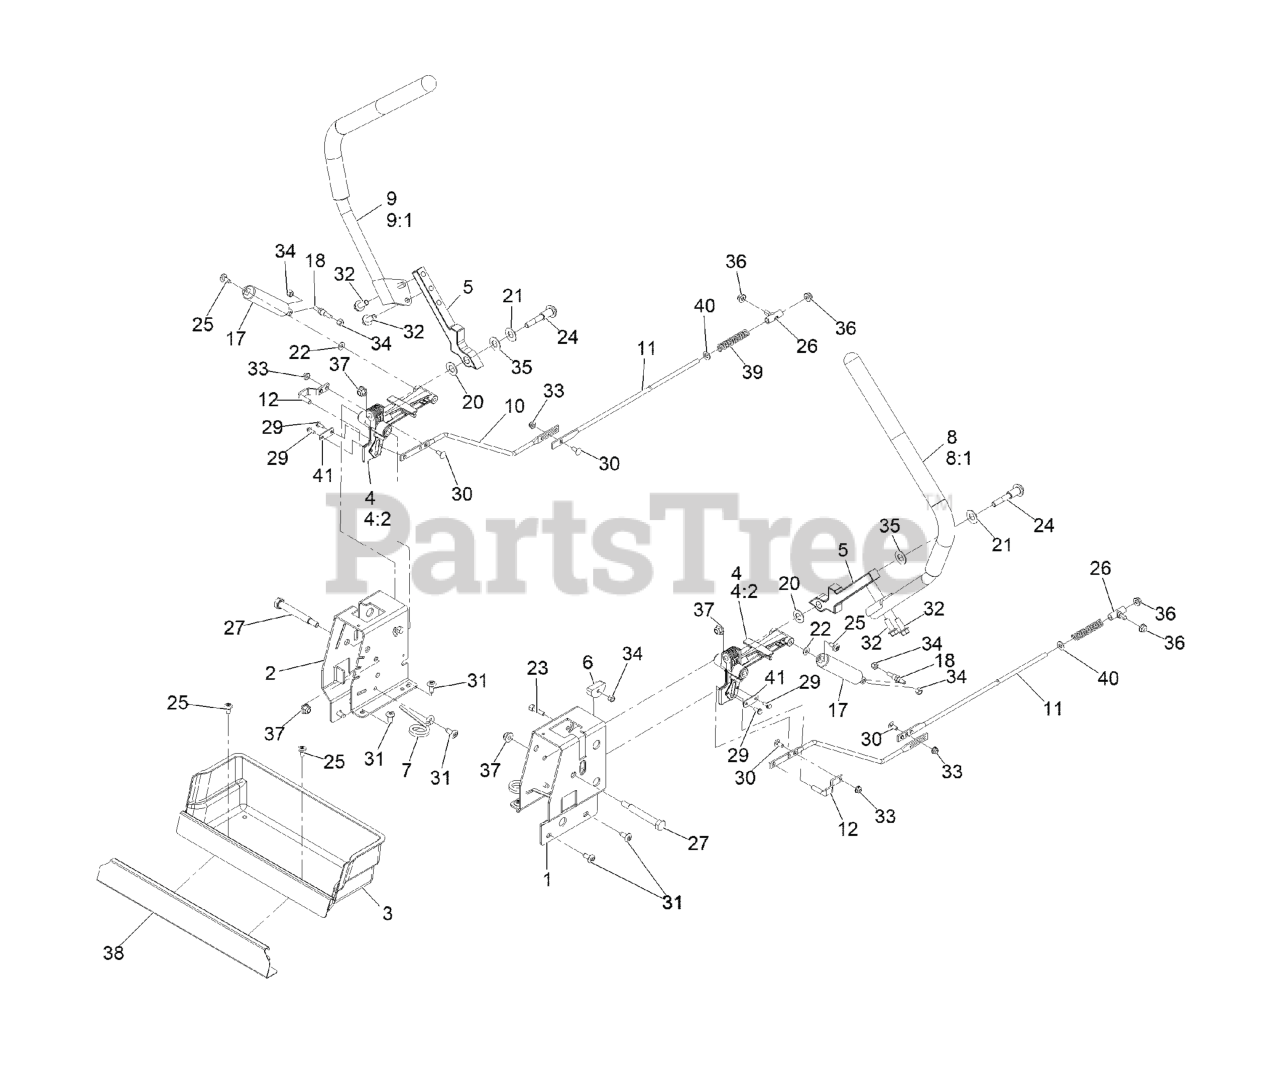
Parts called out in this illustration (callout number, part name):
1	PLATE-CONTROL BOX, LH
2	PLATE-CONTROL BOX, RH
3	BOX, STORAGE
4	ACTUATOR ARM ASM
4:2	BUSHING-FLANGE
5	ARM-CONTROL
6	ECCENTRIC
7	SPRING-TORSION
8	HANDLE-CONTROL, LH
9	HANDLE-CONTROL, RH
10	ROD-HYDRO, FRONT
11	ROD-HYDRO, REAR
12	PIN-ROD, HYDRO
17	DAMPER-NON CAVITATING
18	STUD-DAMPER
20	WASHER-NYLON
21	WASHER-BELLEVILLE
23	BOLT-PIVOT, ECCENTRIC
24	BOLT-PIVOT
25	SCREW-SHOULDER
26	Rod-Hydro
27	BOLT-PIVOT
29	SCREW-TAPTITE
30	SCREW-CARR
32	SCREW-HHF 3/8-16 X 1
34	NUT-LOCK, NI
37	NUT-HF, NI
38	PLATE-KICK
39	SPRING-COMPRESSION
40	WASHER-PLAIN
41	PLATE-STOP, HYDRO
